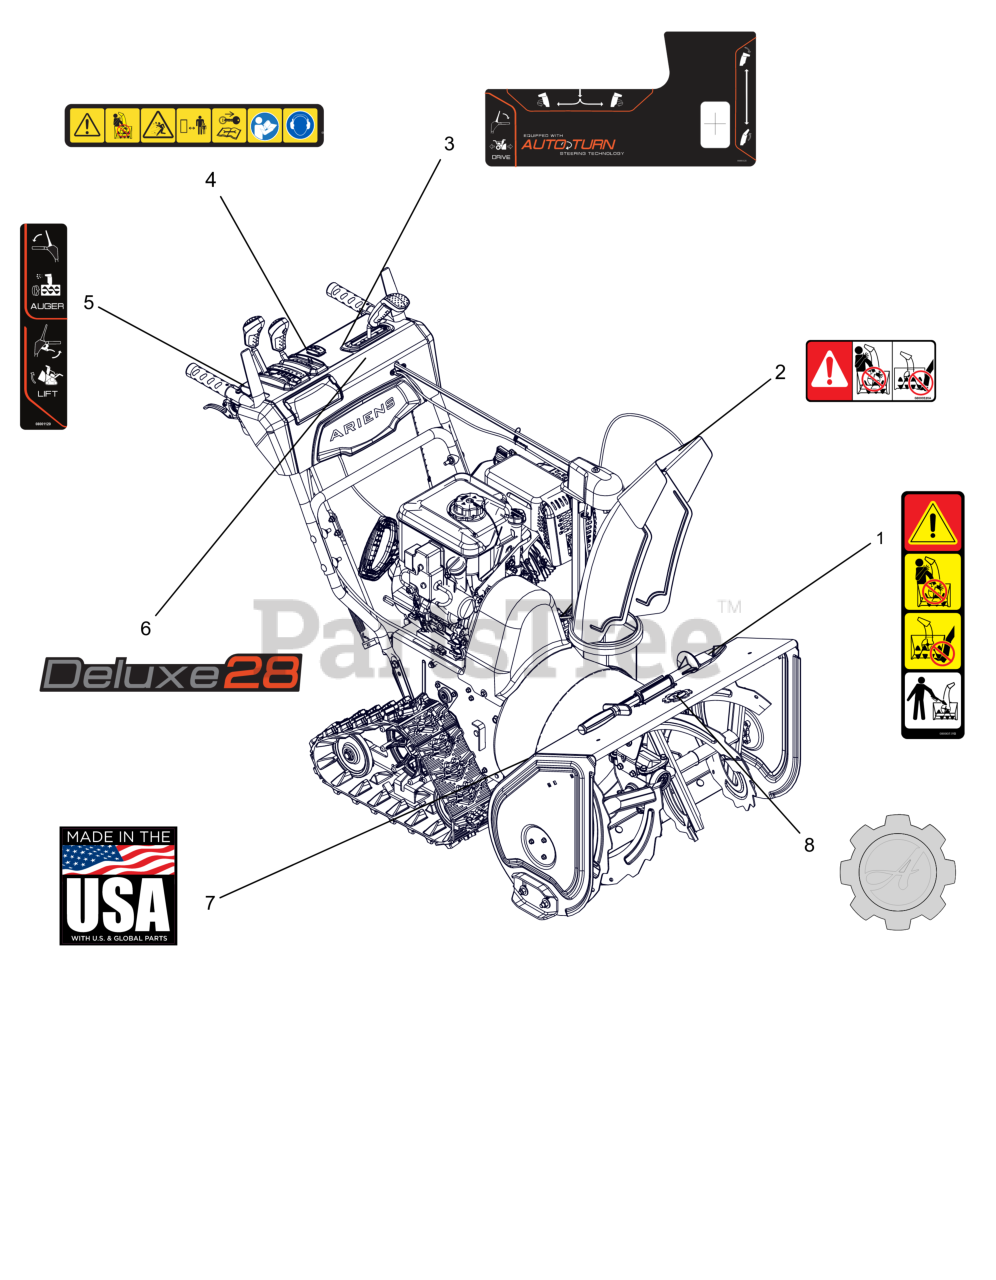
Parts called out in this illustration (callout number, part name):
1	DECAL, DANGER - ROTATING PARTS
2	DECAL, DANGER
3	DECAL,CONTROL-LG QT2
4	DECAL,DASH - SAFETY
5	DECAL,CONTROL-RH TRACK
6	DECAL, DASH - DELUXE 28
7	DECAL, MADE IN USA
8	DECAL, ARIENS-GEAR BADGE -THK
